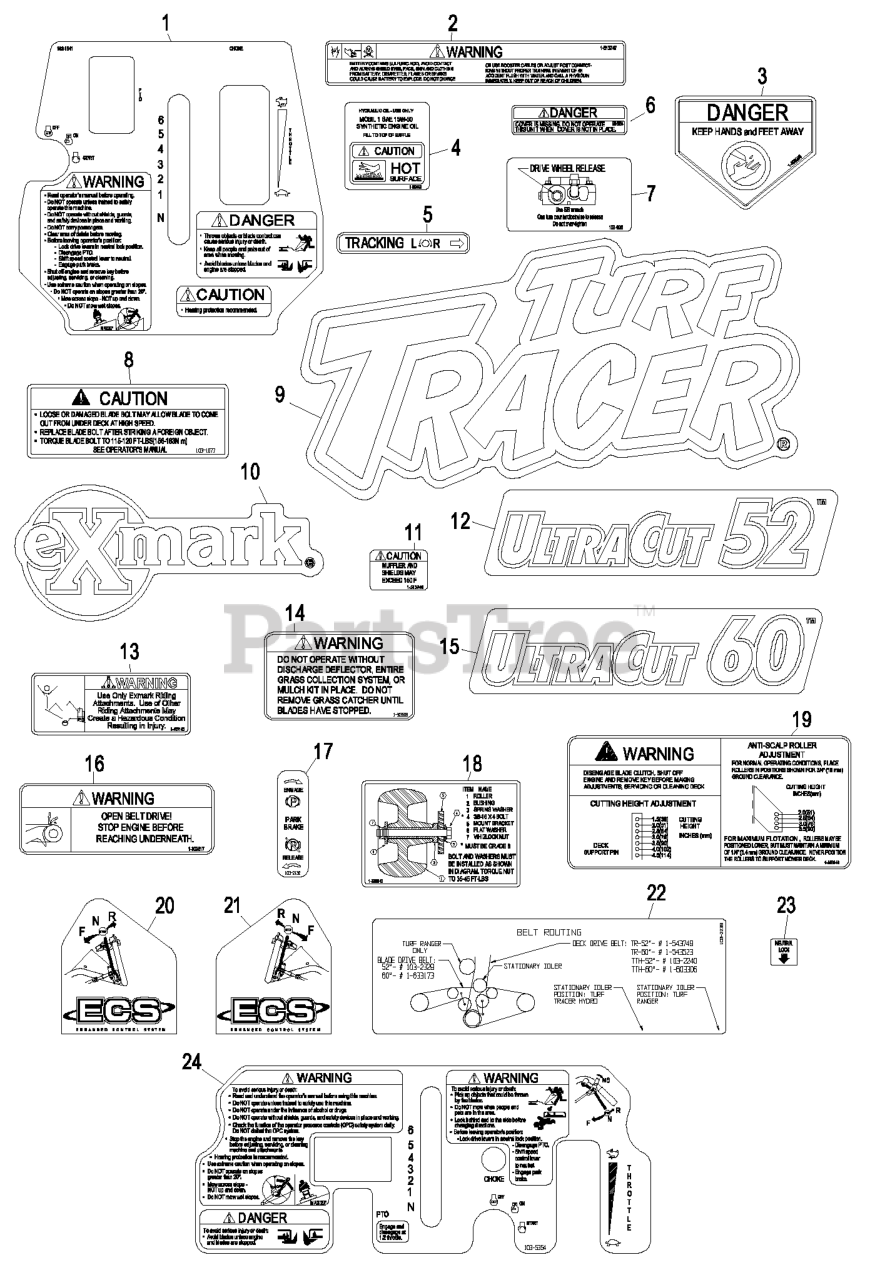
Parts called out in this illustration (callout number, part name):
1	DECAL,TTH ECS CONSOLE
2	DECAL-BATTERY
3	DECAL-DANGER
5	DECAL,TRACKING ADJUST
6	DECAL-COVER, MISSING
7	DECAL,DRIVE RELEASE
8	DECAL,BOLT TORQUE
9	DECAL,TTH MODEL
10	DECAL,EXMARK LOGO
12	DECAL,ULTRACUT 52
13	DECAL,SULKY WARNING
14	DECAL-WARNING, DISCHARGE
15	DECAL,ULTRACUT 60
16	DECAL,BELT DRIVE
17	DECAL,PARKING BRAKE
18	DECAL,ROLLER MOUNTING
19	DECAL,ANTI SCALP
20	DECAL,LH ECS INSTRUCTION
21	DECAL,RH ECS INSTRUCTION
22	DECAL,BELT ROUTING
23	DECAL,NEUTRAL LOCK
24	DECAL,CONSOLE
